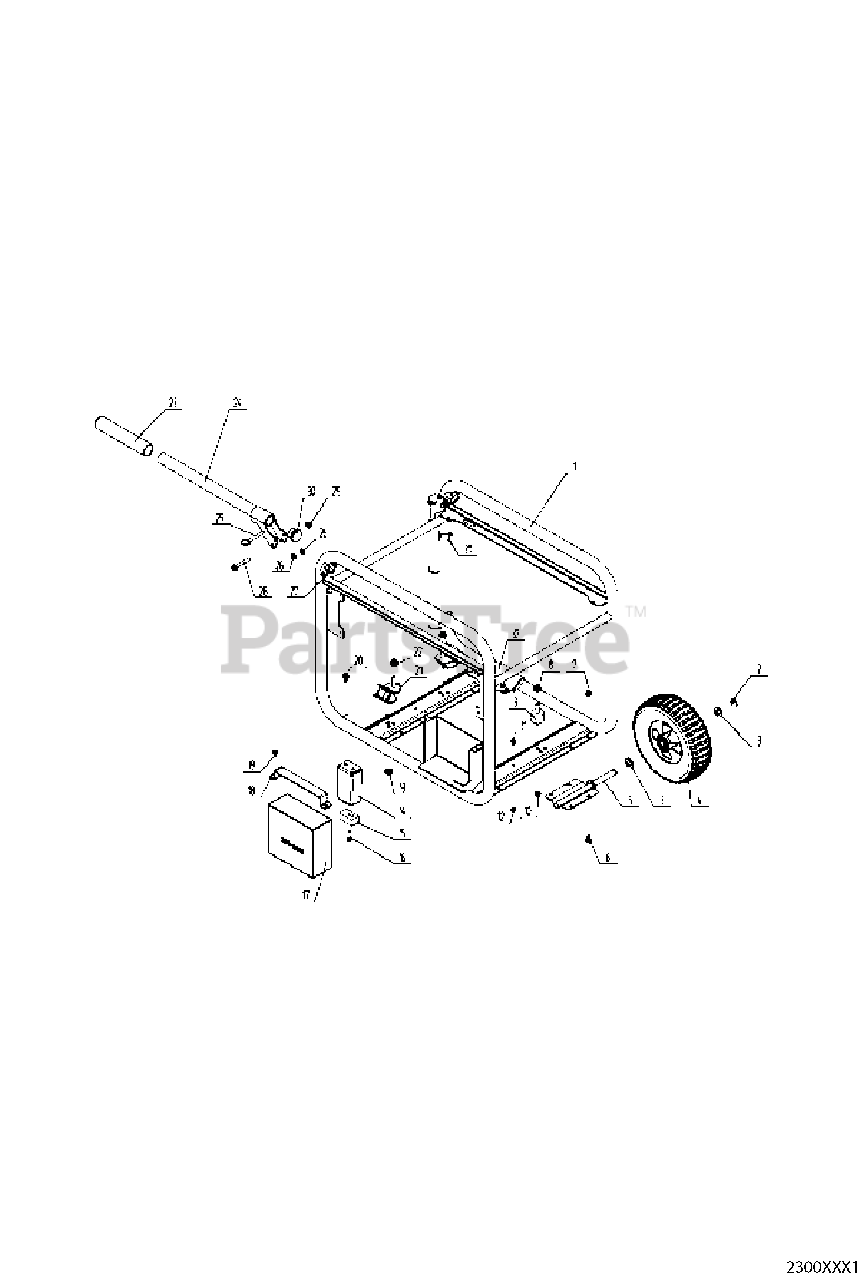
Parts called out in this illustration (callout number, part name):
6	FLANGE BOLT M8X16
7	NUT FLANGE M8
8	HEXAGON NUT M10
10	NUT FLANGE M8
11	SUS FLANGE BOLT M6X10
12	SUS FLANGE NUT
13	HEXAGON NUT M10
16	FLANGE BOLT M6X25
19	HEXAGON FLANGE BOLT M6X12
20	FLANGE BOLT M8X16
22	HEXAGON NUT M10
28	HEXAGON FLANGE BOLT M8X60
